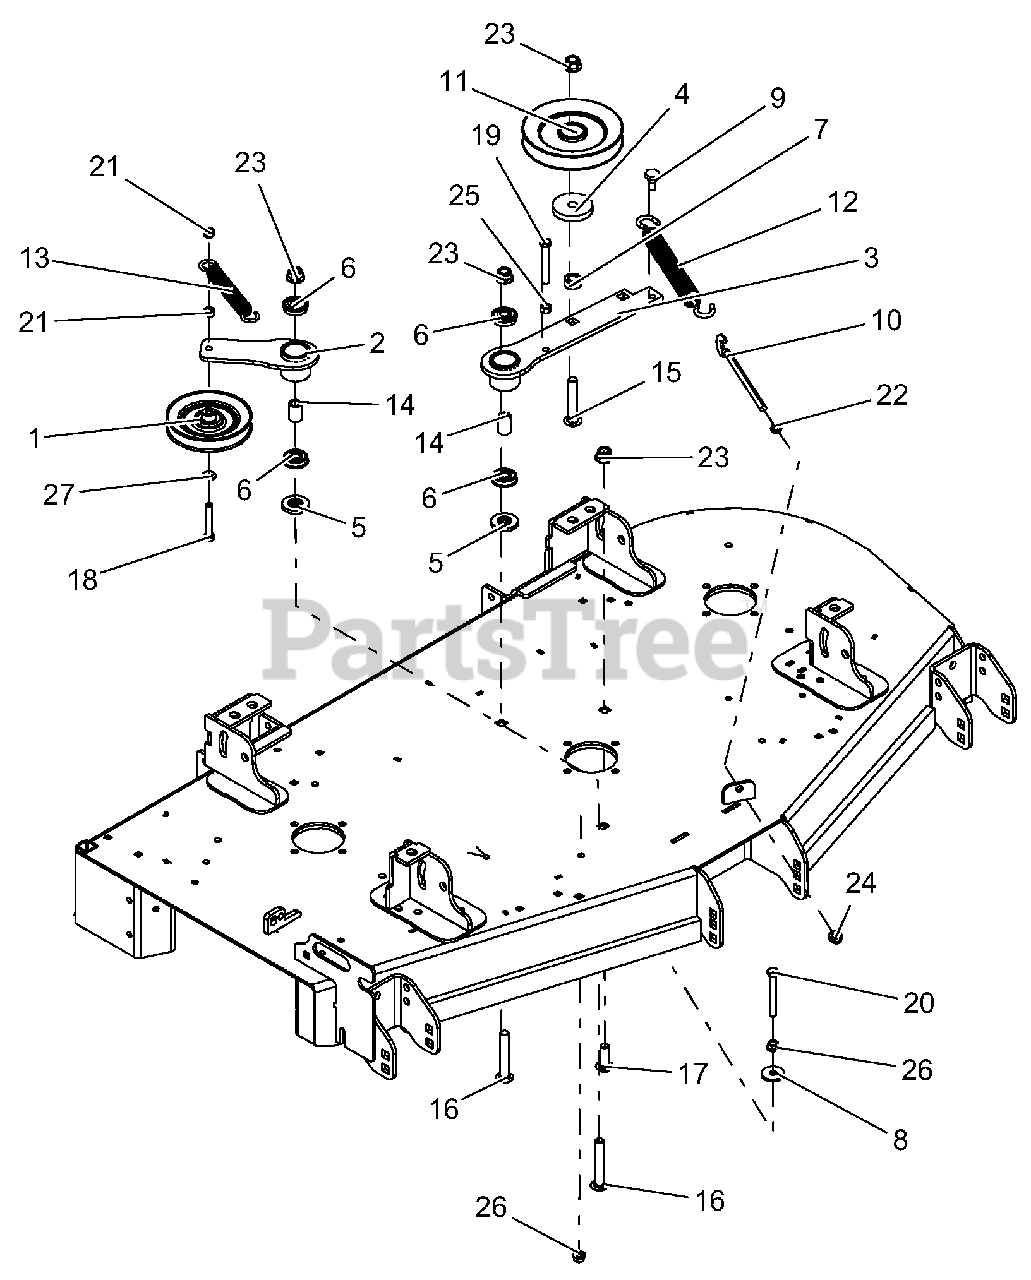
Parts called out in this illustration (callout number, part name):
1	IDLER, V-5.00" W/.69 STANDOFF
2	WLDMT, DECK RH IDLER ARM-BLACK
3	WLDMT, DECK PTO IDLER ARM-BLACK
4	CAP, IDLER BEARING SEALING
5	SPACER, IDLER ARM
6	BRG, BALL .501 X 1.38 X .438 SEALED
7	BSHG, SPCR .502 X .997.50 PM
8	WSHR-FL-STL .406X1.375X.135 YZ
9	BLT, SHLDR EP .38-16X.30 HEX YZ
10	BOLT, .38-16X6.00 .62 DIA EYE
11	SHEAVE, .50" ID X 6.00" OD V-IDLER
12	SPRG, EXTENSION
13	SPRG, EXTENSION
14	SPACER, .510 X .750 X 1.148
15	BLT-RDHDSQNK .50-13X3.00YG5
16	BLT-RDHDSQSHNK .50-13X3.25 YWZC
17	BLT-RDHDSQSHNK .50-13X1.50 YWZC
18	BLT-HEX .38-16X2.25 GR5 YWZC
19	BLT-HEX .38-16X2.75 GR5 YWZC
20	BLT-HEX .38-16X3.00 GR5 YWZC
21	NUT-LK-CTR .38-16 YWZC
22	NUT, JAM .375-16 YWZC
23	NUT-LK-NYL-FLG .50-13 YWZC
24	NUT-LK-NYL-FLG .38-16 YWZC
25	NUT-HEX .38-16 YWZC
26	@NUT-SPNLK-FLG .375-16 YWZC
27	WSHR-FL-STL.406X.812X.065 YWZ
